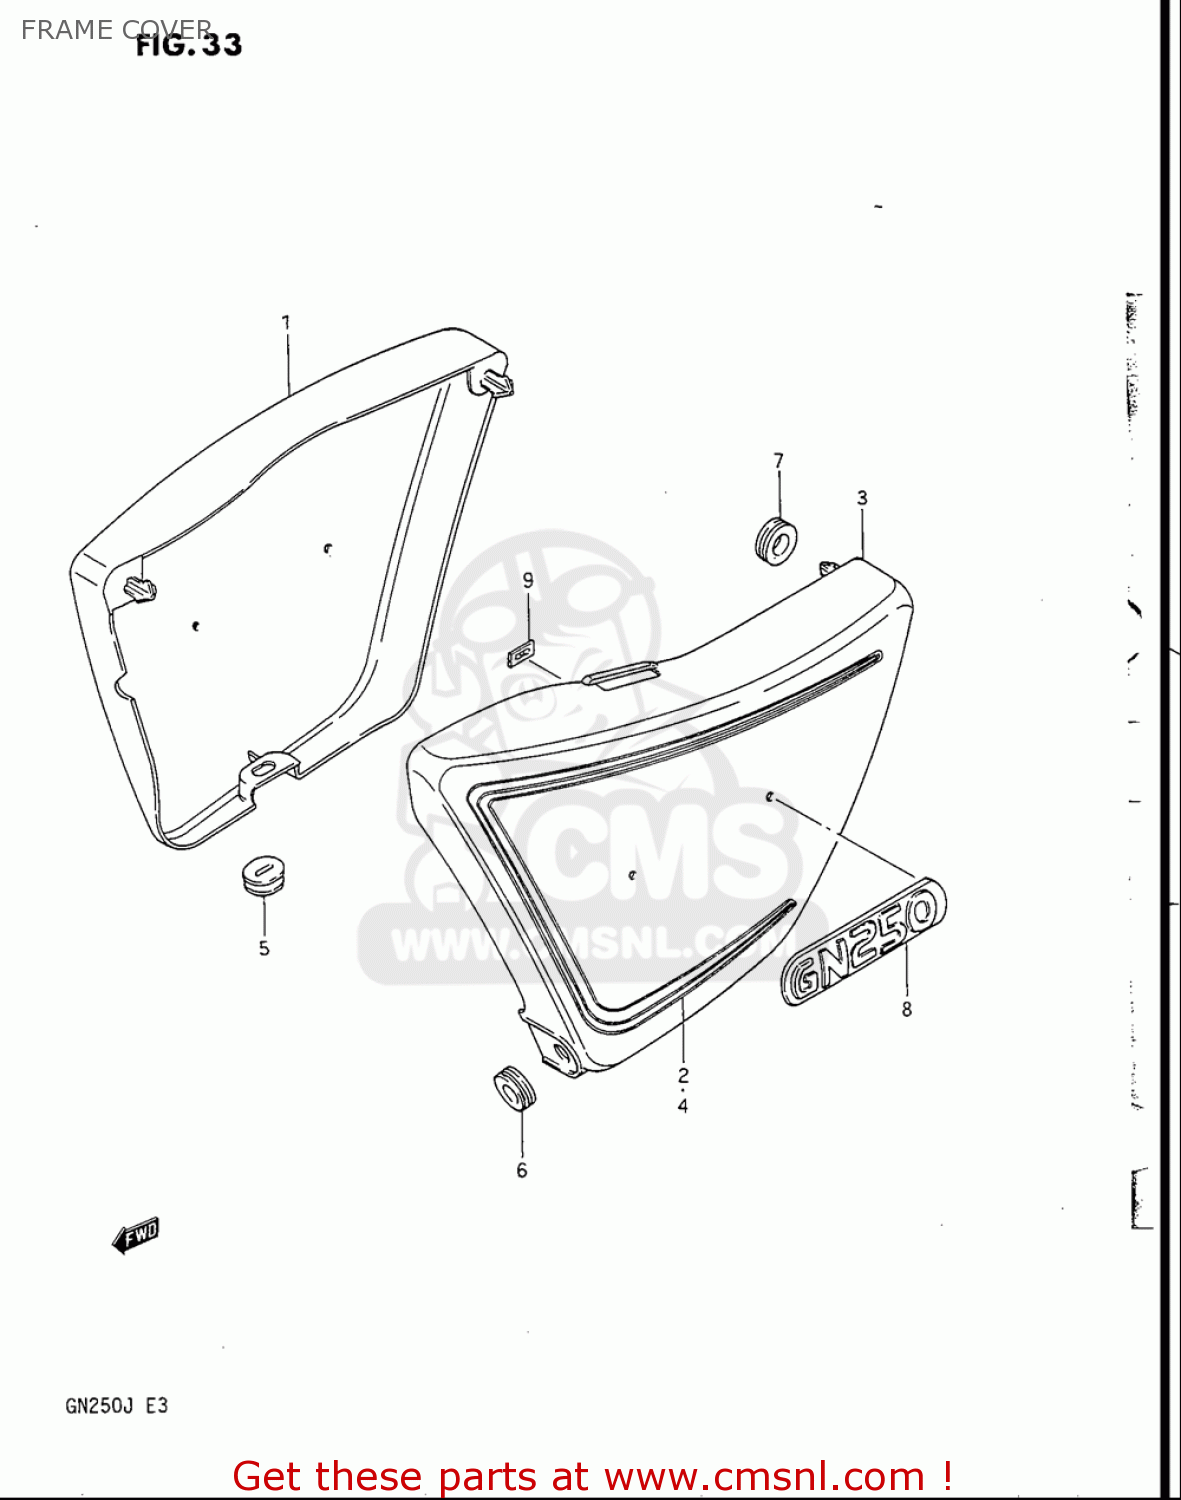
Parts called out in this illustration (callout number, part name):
1	COVER,FRAME,RIGHT
3	COVER,FRAME,LEFT
4	TAPE SET,FRAME COVER,L
5	CUSHION
6	CUSHION
7	CUSHION
8	EMBLEM,GN250
9	NUT
